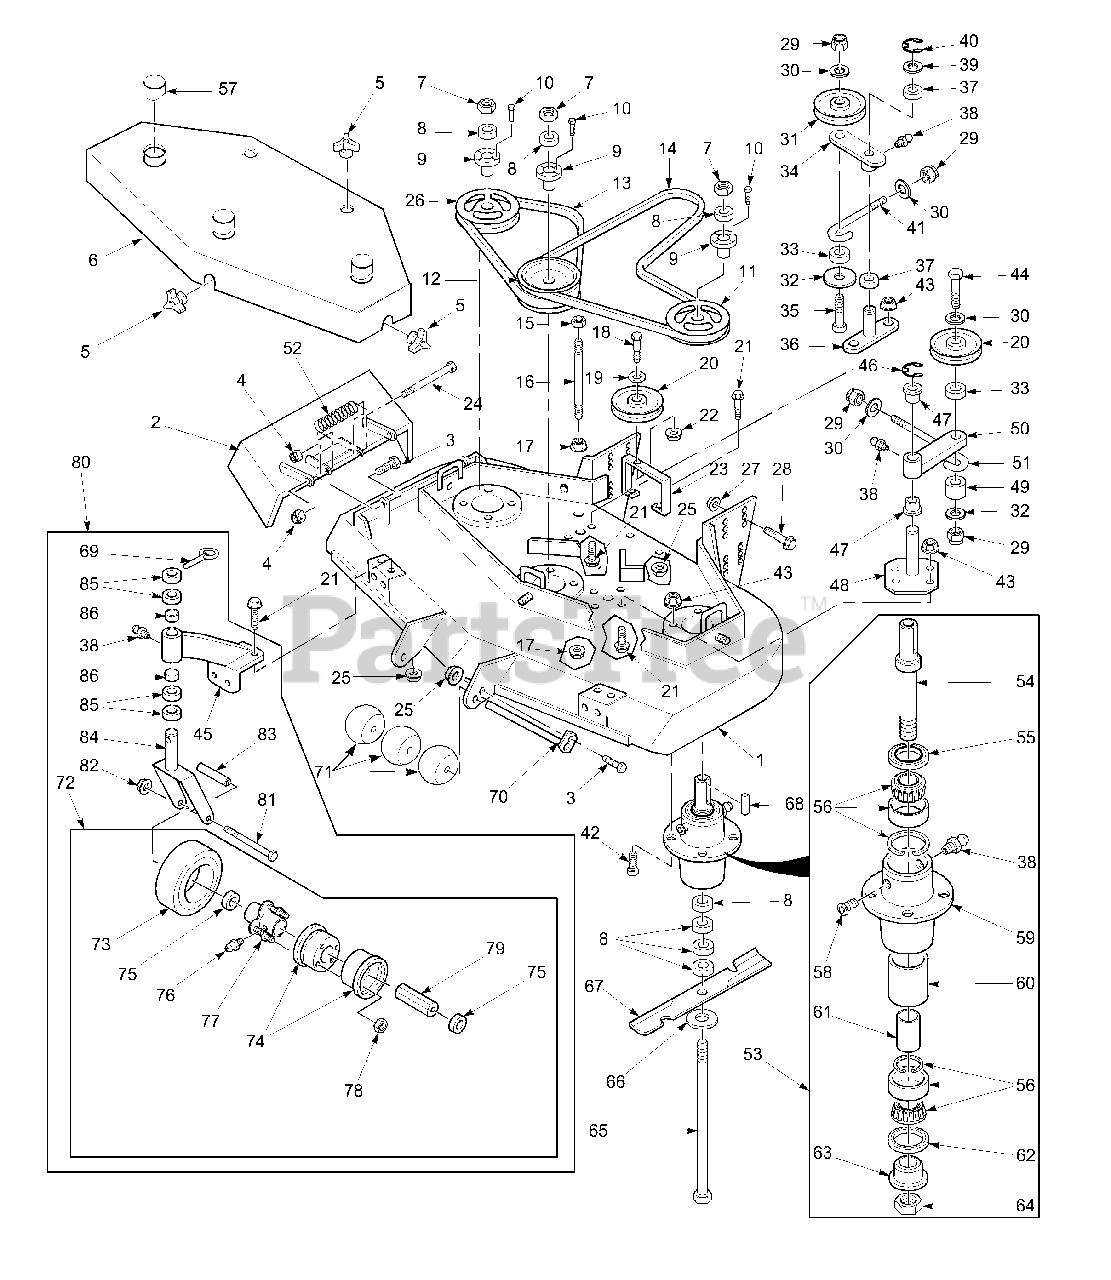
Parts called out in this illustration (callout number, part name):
1	Cutter Deck, Advantage
2	Discharge Chute, Advantage
3	Bolt, 5/16-18 x 1" Hex Head
4	Nut, 5/16-18 Elastic Stop
5	Wing Nut, 3/8-16
6	Belt Cover
7	Nut, 5/8-11 Hex Head
8	Spacer, Cutter Blade
9	Tapered Hub, 1.125 Bore
10	Bolt, 1/4-20 x 3/4 Hex Head
11	Pulley, 6.95 O.D.
12	Pulley, Double Groove, 6.95/5.75 O.D.
13	Belt, R.H. Blade Drive
14	Belt, Deck Drive
15	Lock Nut,3/8-16 Hex Head
16	Stud, 3/8-16 x 6-3/4"
17	Nut, 3/8-16 Serr. Flange
18	Bolt, 3/8-16 x 2-1/4"
19	Flatwasher, 3/8 (.391 x .938 x .105)
20	Pulley, Belt Guide
21	Capscrew, 5/16-18 x 3/4 Ser. Flg. HH
22	Nut, 3/8-16 Elastic Stop
23	Idler Pulley Support
24	Bolt, Hex Head 5/16-18 x 4-1/4"
25	Nut, 5/16-18 Ser. Flg. Hex Hd.
26	Pulley, 5.75
27	Nut, 1/2-13 Ser. Flg. Hex Hd.
28	Capscrew, 1/2-13 x 1-1/4 Ser. Flg.
29	Nut, 3/8-16 Elastic Stop
30	Flatwasher, 3/8 (.391 x .938 x .105)
31	Pulley
32	Flatwasher, 3/8 (.375 x 1.50 x .060)
33	Spacer
34	Idler Arm
35	Bolt, 3/8-16 x 2-1/4"
36	Idler Pivot
37	Bushing, Bronze Oilite-3/4 ID
38	Grease Fitting, Str. 1/4-28 Self Tap.
39	Flatwasher, 3/4 (.776 x 1.25 x .059)
40	Retaining Ring, .75 EXT 'E'
41	J-Rod Idler Pulley
42	Bolt, 5/16-18 x 1-1/4" Hex Head
43	Nut, 5/16-18 Ser. Flange
44	Bolt, 3/8-16 x 3-1/2" Hex Head
45	Support Assembly
46	Retaining Ring, 1-1/8 EXT 'E'
47	Bushing, Bronze Oilite- 1-1/8 ID
48	Idler Pivot Support
49	Spacer
50	Idler Arm
51	J-Rod, Drive Idler
52	Spring, Chute Return
53	Spindle Assembly
54	Shaft, Cutter Spindle
55	Seal, 2.00 O.D. x 1.50 Bore
56	Bearing Assembly
57	Shield, Spindle
58	Relief Fitting, Cutter Spindle
59	Spindle Housing
60	Spacer, Outside
61	Spacer, Inside
62	Seal, 2.00 O.D. x 1-5/8 Bore
63	Spindle Bushing Bottom
64	Nut, 1-1/16-18 UNEF-2B
65	Bolt, 5/8-11 x 9-1/2"
66	Flatwasher, 5/8 (.688 x 1.75 x .134)
67	Cutter Blade, 24"
68	Key, 1/4 x 1/4 x 2"
69	Quick Pin
70	Shaft, Roller
71	Guide, Roller
72	Wheel Assy., Caster
73	Tire Only, Caster Wheel
74	Rim Pair, Caster Wheel
75	Retainer, Caster Wheel
76	Grease Fitting, 45 Deg. 1/4-28
77	Hub Assy. W/Bolts, Caster Wheel
78	Tapered Hex Nut, 5/16-18
79	Roller Bearing, Caster Wheel
80	Caster Wheel Assembly
81	Bolt, 1/2-13 x 5-1/2" Hex Head
82	Nut, 1/2-13 Elastic Stop
83	Sleeve, Caster Wheel Bearing
84	Caster Yoke
85	Spacer, Caster Yoke 1/2"
86	Bushing, 7/8 x 1" Flanged
